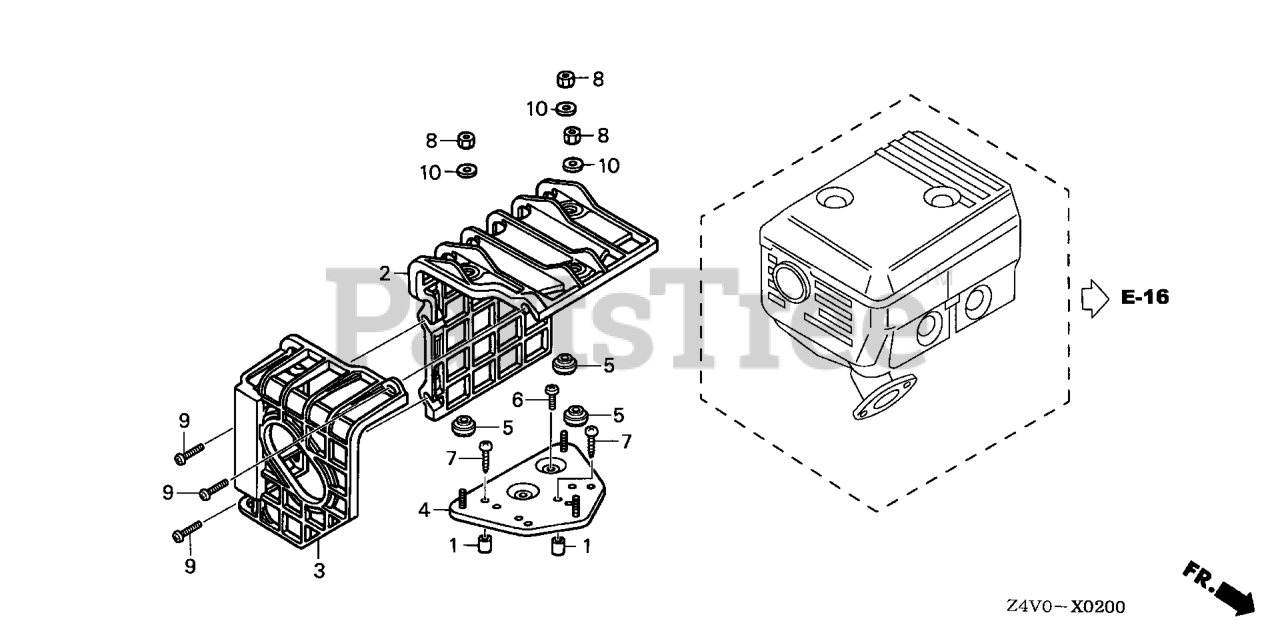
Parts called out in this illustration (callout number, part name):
1	COLLAR, AIR CLEANER HOUSING
2	COVER, MUFFLER
3	COVER, RR. MUFFLER
4	BASE, MUFFLER COVER
5	SPACER, MUFFLER COVER
6	SCREW, TAPPING (5X8)
7	SCREW, TAPPING (5X25)
8	NUT, HEX. (5MM)
9	SCREW-WASHER (6X20)
10	WASHER, PLAIN (5MM)
